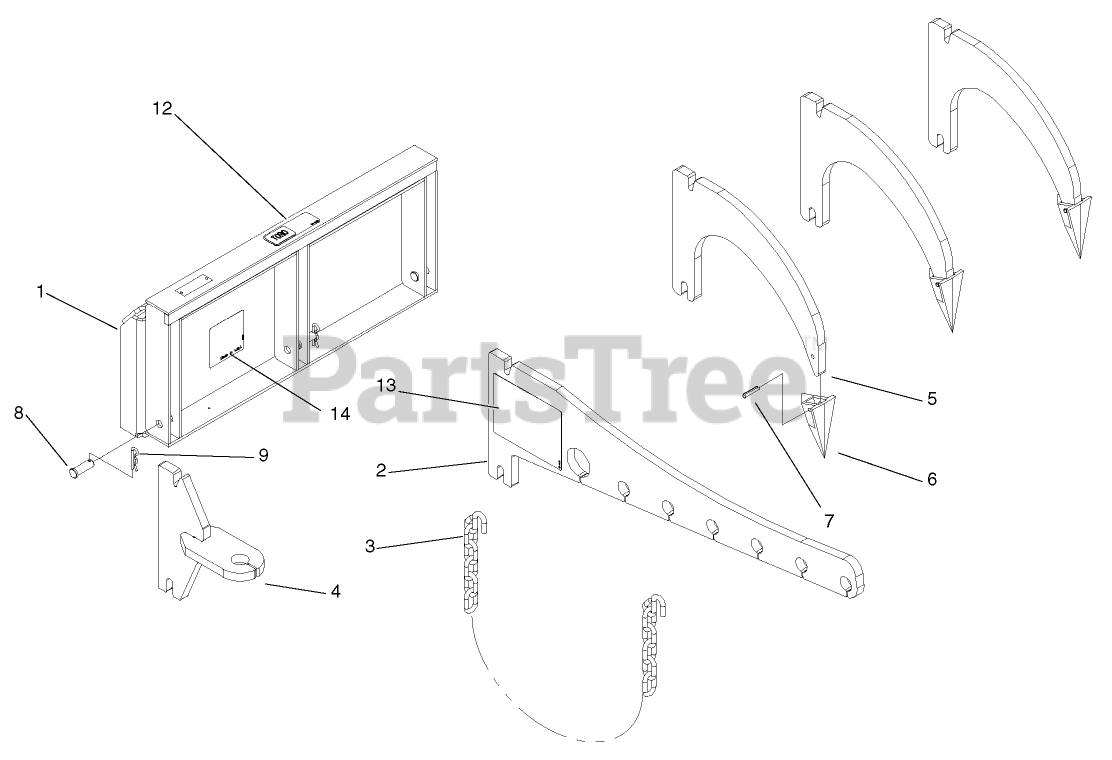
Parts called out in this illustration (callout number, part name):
1	CARRIER TOOL ASM
3	CHAIN-LIFT
4	TOW BAR ASM
5	PLATE-TYNE
6	POINT-Spear
7	PIN-SPRING
8	PIN-CLEVIS
9	PIN-HAIR
12	DECAL-ATTACHMENT, DINGO
13	DECAL-RATING, LOAD
14	DECAL
